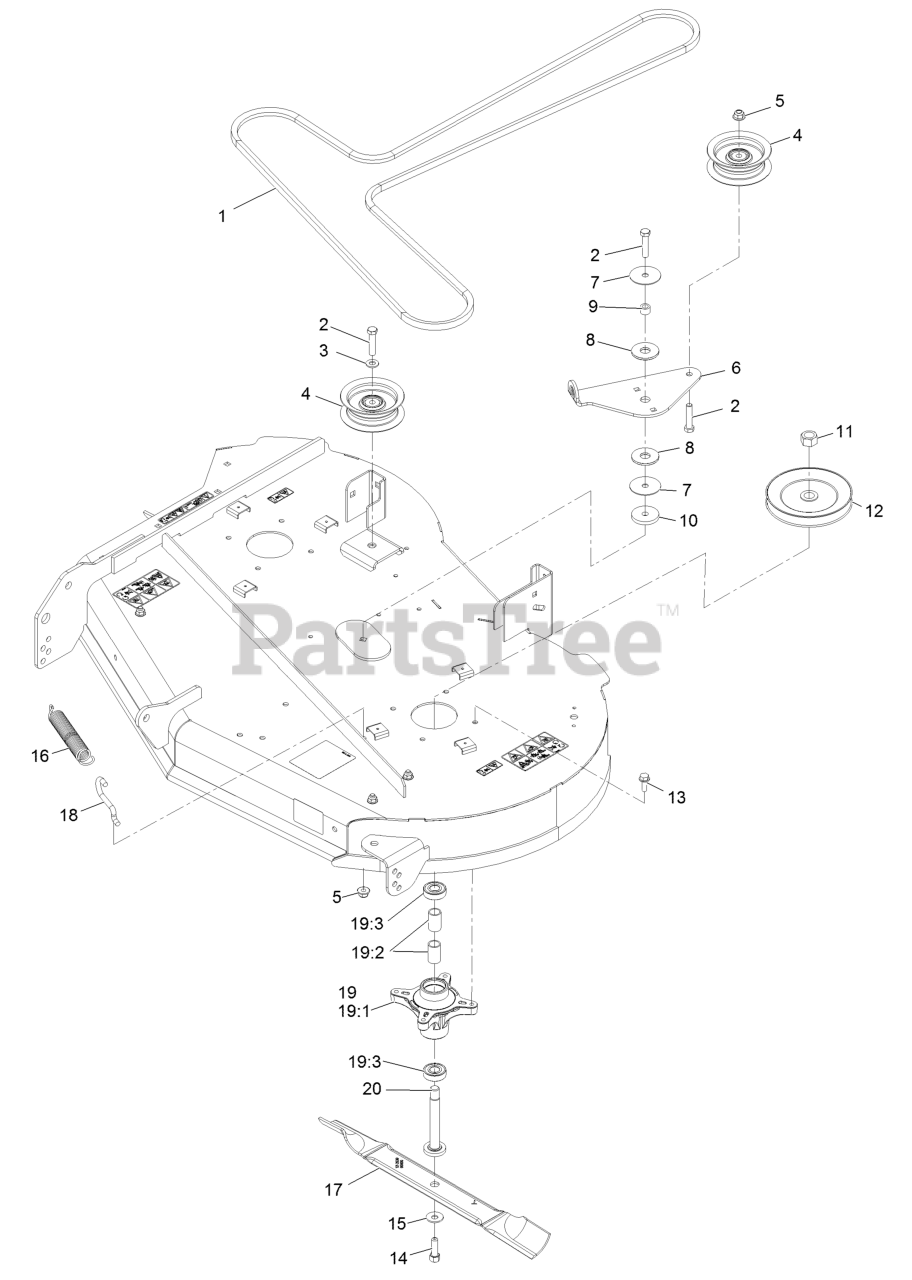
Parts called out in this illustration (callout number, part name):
1	V-BELT
2	SCREW-HH
3	WASHER-FLAT
5	NUT-HF, NI
6	ARM-IDLER
8	WASHER-FRICTION, COMPOSIT
10	WASHER-PLAIN
11	NUT-HEX
12	PULLEY
13	SCREW-TAPTITE
14	SCREW-HH
15	WASHER-BELLEVILLE
16	SPRING-EXTENSION
17	BLADE-HIGH LIFT
18	HOOK-RETURN, SPRING
19	SPINDLE ASM
20	SHAFT-SPINDLE
